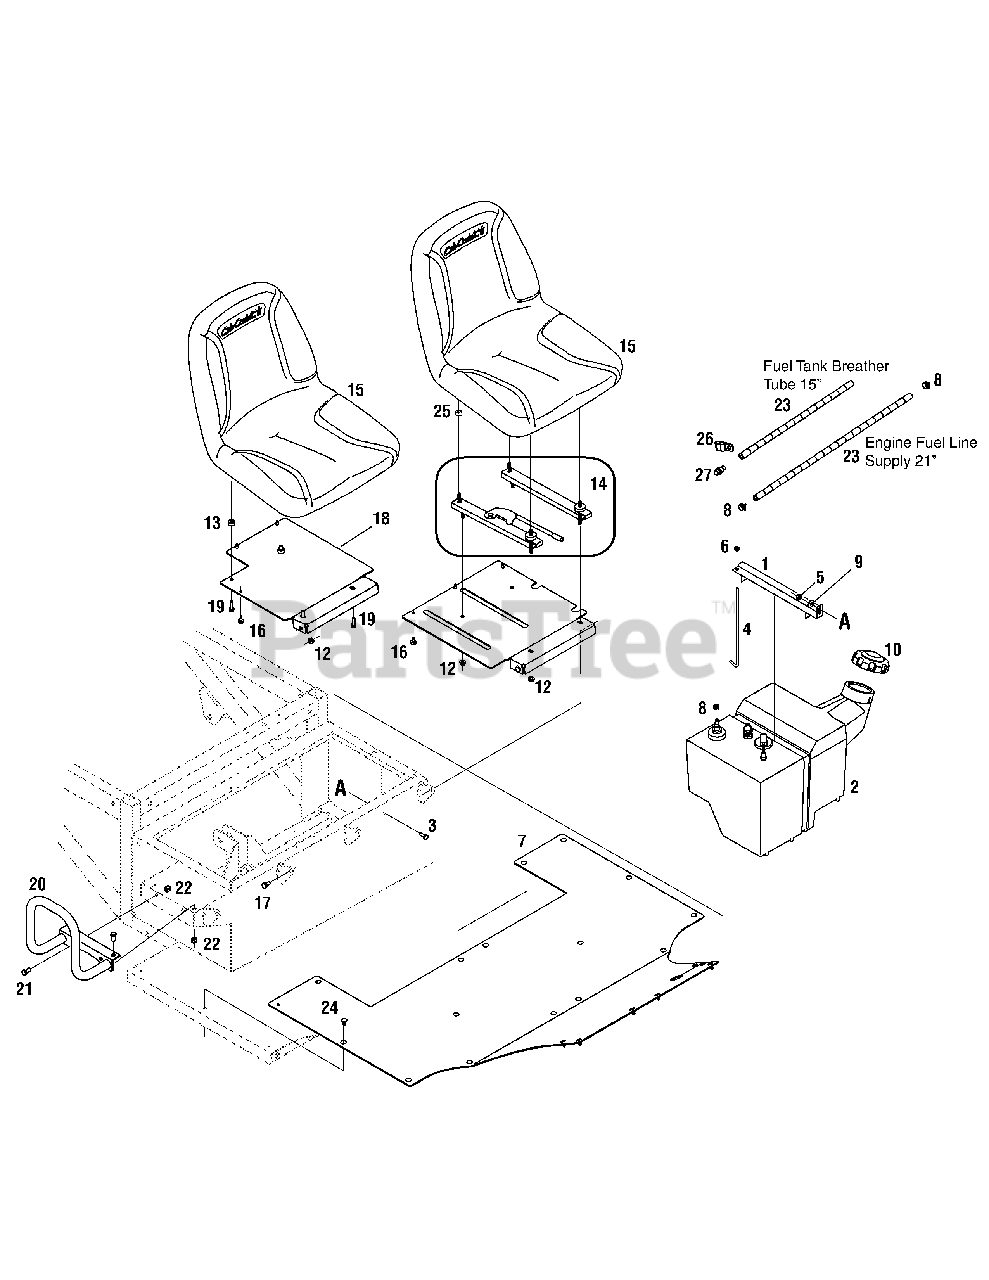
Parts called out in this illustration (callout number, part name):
1	Bracket Assembly, Fuel Tank
2	Tank Assembly, Fuel
3	Hex Screw, 5/16-18 x .75
4	Hold-down Rod, Fuel Tank
5	Sems Nut, 5/16-18
6	Nut, Flange Lock, 1/4-20
7	Mat, Floor
8	Clamp, Hose
9	Washer, .349 x .879 x .063
10	Cap, Fuel
11	Plate, Seat, LH
12	Nut, Flange Lock, 5/16-18, Gr5
13	Spacer, Seat
14	Track Assembly, Seat
15	Seat
17	Shldr Scr, .435 x .178-5/16 x .
18	Plate, Seat, RH
19	Hex Screw, 5/16-18 x 1.0
22	Nut, Hex Lock Nylon, 3/8-16
23	Hose, Fuel Line
24	Clip, Retainer, .250 x .267
25	Spacer, Seat
26	Clamp, Double Tube
27	Vent, 3/8 Dia.
